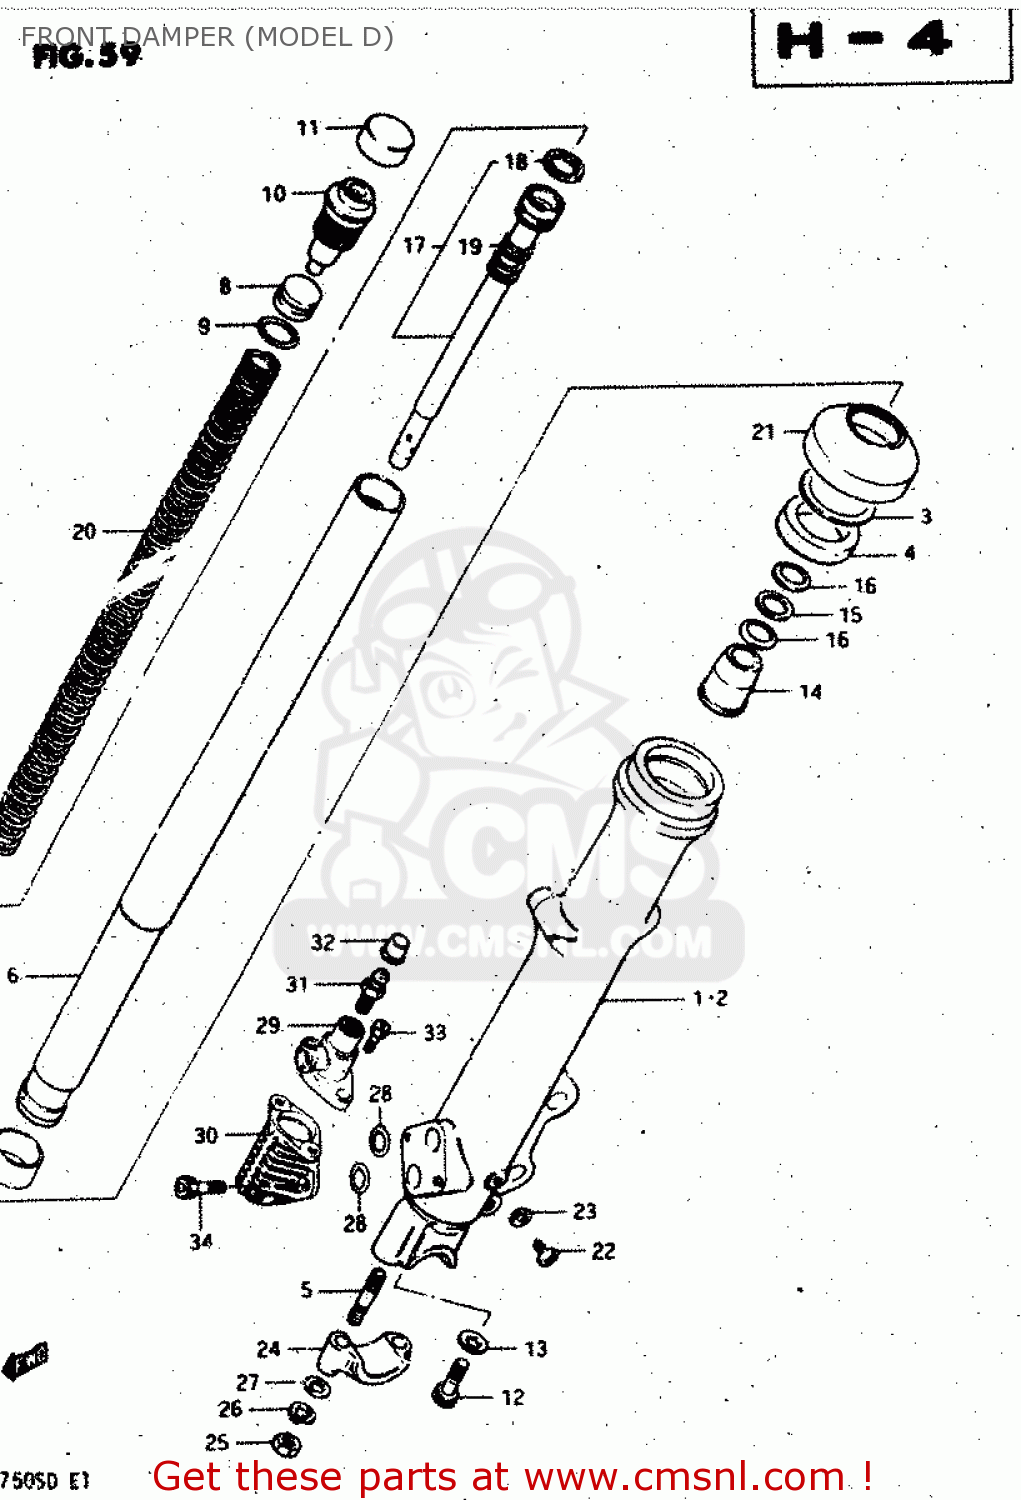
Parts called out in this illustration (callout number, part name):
1	TUBE,FORK,OUTER,RIGHT
2	TUBE,OUTER,LEFT
3	RING,STOPPER
4	OIL SEAL,FRONT FORK
5	STUD 8X30
6	TUBE,INNER
7	PISTON
8	PISTON,FREE
9	O-RING
10	CAP
11	CAP,RUBBER
12	BOLT,FORK CYLINDER(10X25)
13	GASKET (NAS)
14	PIECE,OIL LOCK
15	WASHER
16	SPRING,LEAF
17	CYLINDER,FRONT FORK
18	RING,PISTON
19	SPRING,REBOUND
20	SPRING,FRONT FORK
21	SEAL,DUST
22	SCREW
23	GASKET,DRAIN,PLUG (NAS)
24	HOLDER,AXLE
25	NUT
26	LOCK WASHER
27	WASHER
28	O RING
29	PLANGER SET,MODULATOR
30	VALVE SET,MODULATOR
31	BREATHER,AIR
32	CAP,BREADER
33	BOLT, MODULATOR (5X12)
34	BOLT,FRONT FORK
